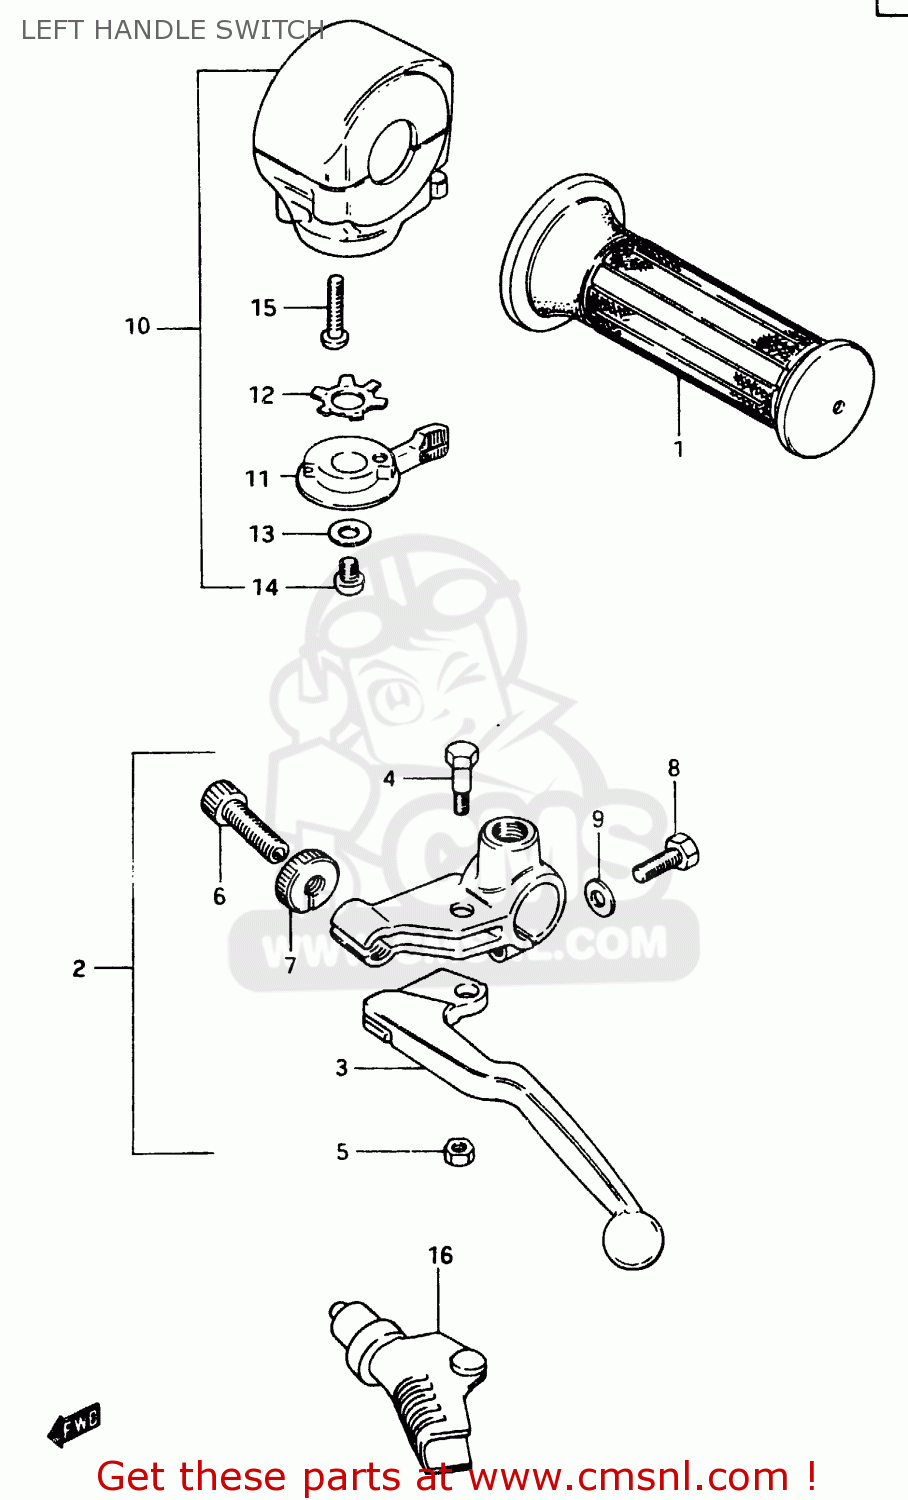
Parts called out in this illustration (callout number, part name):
1	GRIP,L
2	LEVER ASSEMBLY,CLUTCH
3	LEVER,CLUTCH
4	BOLT,LEVER PIVOT
5	NUT 6MM
6	ADJUSTER,CABLE
7	NUT,CABLE ADJUSTER LOCK
8	BOLT,CLUTCH LEVER HOLDER
9	WASHER
10	SWITCH ASSY,HA
11	LEVER,STARTER
12	WASHER
13	WASHER 6MM
14	SCREW
15	SCREW
16	COVER
